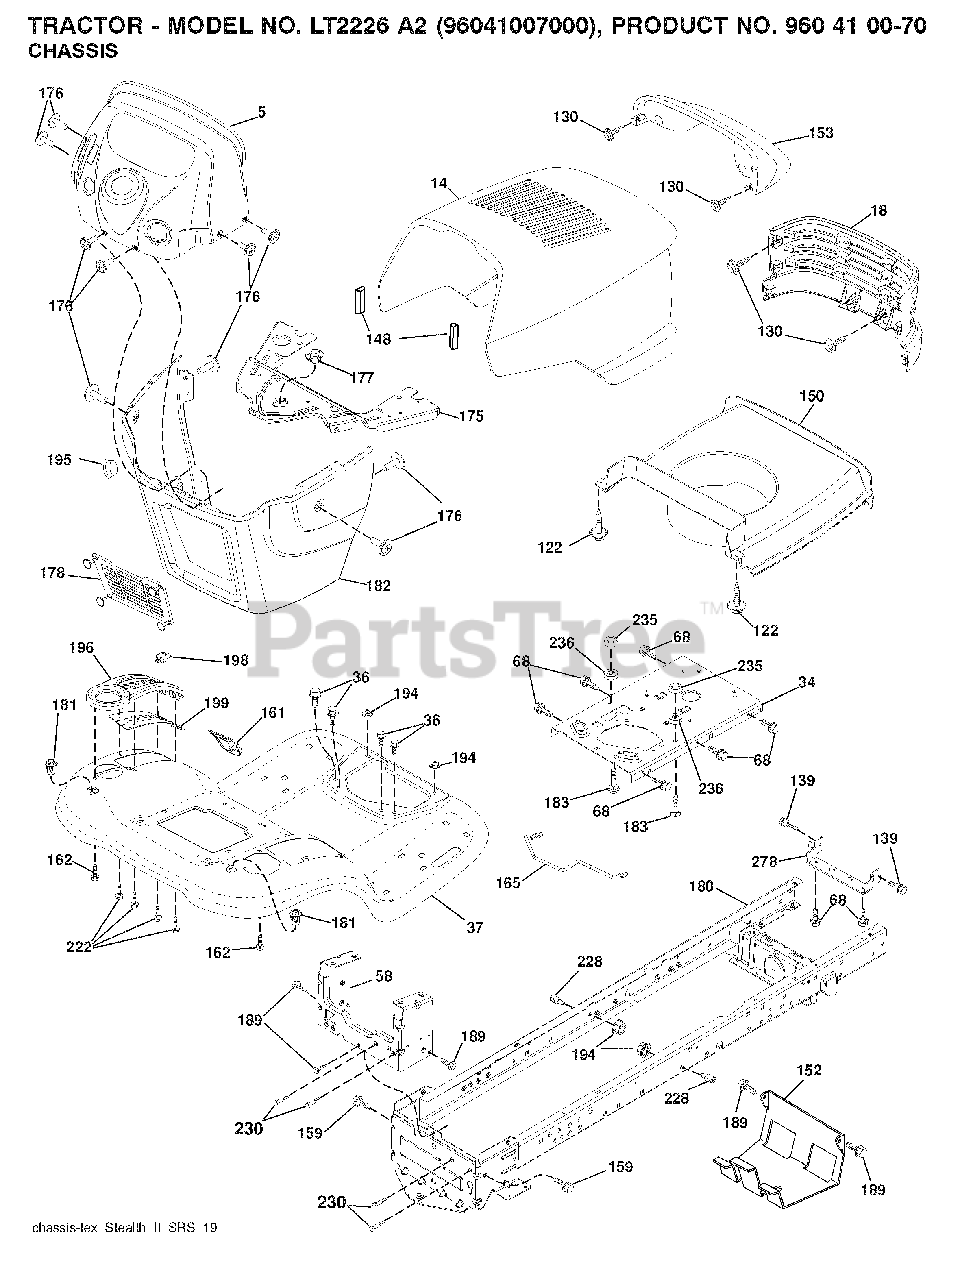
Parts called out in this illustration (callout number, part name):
34	PLATE.ENGINE.WELDED.CHASSIS
36	SCREW 5/16"
58	DRAWBAR.UPPER.2PC,LRG.FENDER
122	SCREW.WSHD.HEX10-32X5/8
130	SCREW.#10 X 0.750.BOS THREAD
139	BOLT, SHOULDER 5/16-18
148	EXTRUSION BUMPER
150	DUCT HOOD
152	SHIELD BROWNING
159	SCREW, 3/8-16X3/4
161	CONSOLE.FUEL.WINDOW.STGT.BLACK
162	SCREW.HI-LO.CONSOLE
165	SUPPORT.TANK.REAR.W/TE
175	CROSSMEMBER.
176	SCREW.#10-24X5/8.RN.QU
177	BUSHING,STEERING
178	CARGO.ASM.NET.DASH.LOWER
180	CHASS.WLDMNT.TLT.12GA/2PC.20"
181	FEND/FTRST.PCH.CPH.NFW
182	DASH.LOWER.
183	BOLT.5/16-18X1-1/4 FULL.THREAD
189	SCREW
194	NUT LOCK HEX FLANGE 5/16-18
195	PLUG.HOLE.DASH.LOWER.12V.BLK
198	INDICATOR DECK LIFT
199	PLATE DECK LIFT
222	SCREW.1/4-20X5/8
228	STUD.FASTNER.W/ANTI-ROTATE
230	SHOULDER BOLT 5/16-18TT
235	SPACER FENDER
236	NUT.CENTERLOCK.5/16-
278	BRKT.HOOD/MUFF.STEALTH
